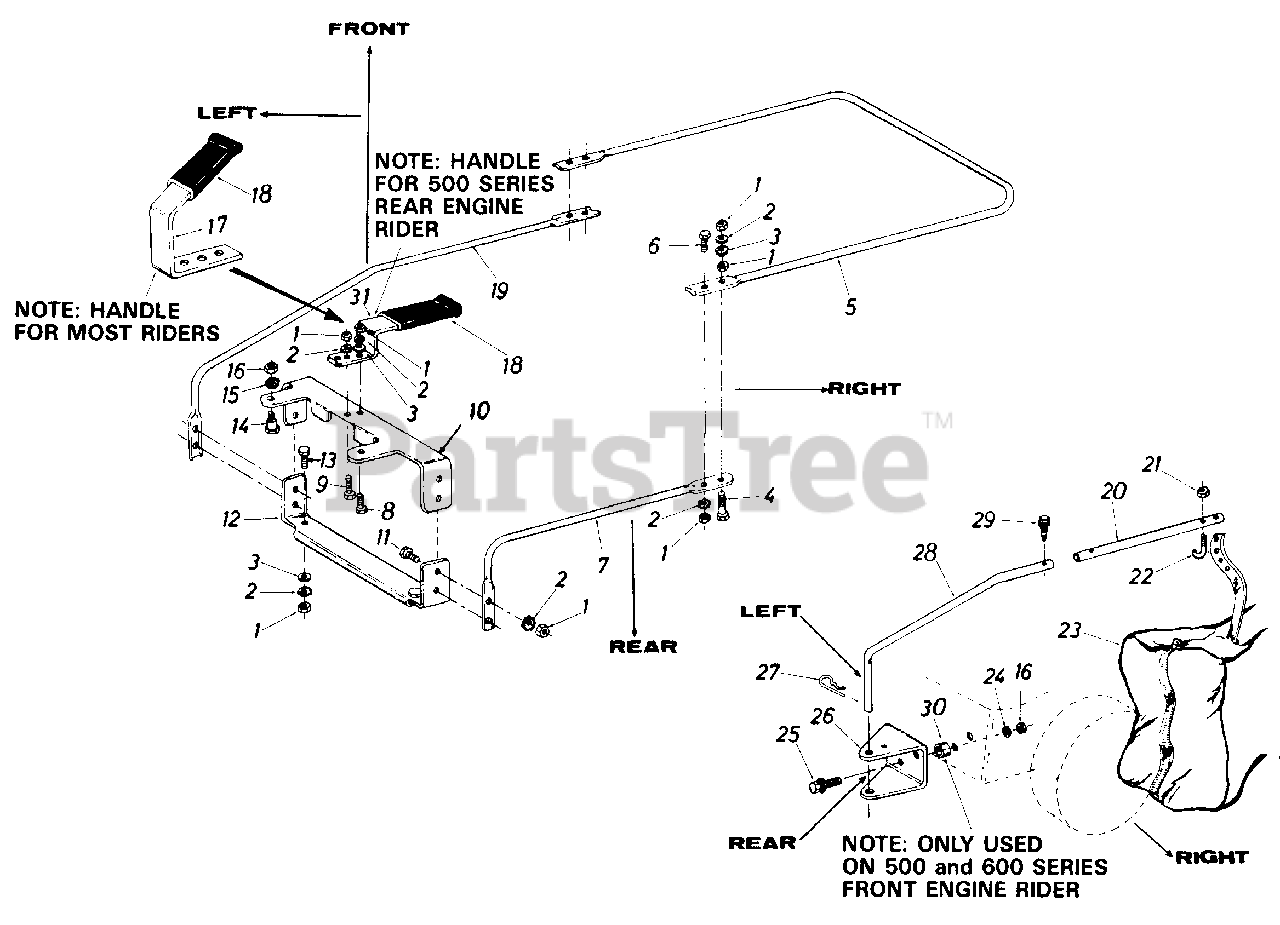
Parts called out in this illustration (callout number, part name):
1	Hex Nut 1/4-20 Thd.*
2	Ext. L-Wash. 1/4" Scr.*
3	Fl-Wash. .281 I.D. x .50 O.D.
4	Hex Scr. 1/4-20 x 1.50" Lg.*
5	Upper Frame Half
6	Hex Scr. 1/4-20 x 1.00" Lg.*
7	Lower Frame Tubing
8	Hex Scr. 1/4-20 x .75" Lg.
9	Hex Scr. 1/4-20x .75" Lg.*
10	Upper Opening Support
11	Hex Scr. 1/4-20 x 1.0" Lg.*
12	Lower Opening Support
13	Hex Scr. 1/4-20 x .50" Lg.*
14	Shld. Scr. .437 Dia. x .350
15	Ext. L-Wash. 5/16" Scr.*
16	Hex Nut 5/16-18 Thd.*
19	Lower Frame Arm
23	Grass CatcherBag
24	L-Wash. 5/16" I.D.*
25	Hex Sems Scr. 5/16-18 x .75" Lg.*
26	Hitch Bracket
27	InternalCoterPin5/8" Dia.
28	Lower HoldingArm
29	Hex Wash. Hd. Self-Tap .50" Lg.
30	Spacer
31	Handle
